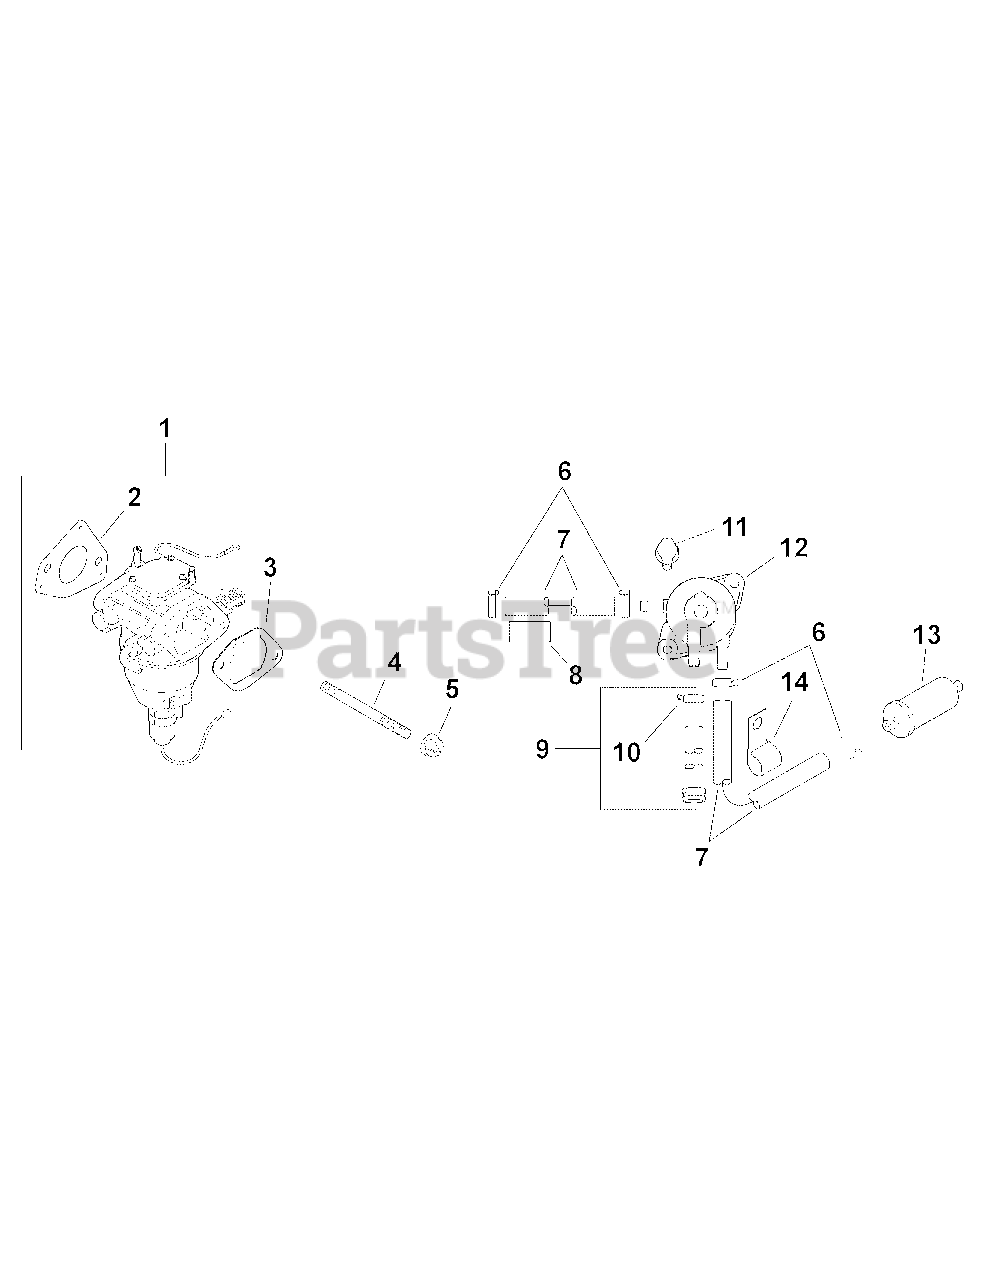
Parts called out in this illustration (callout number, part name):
1	Kit, Carburetor (Incl. 2-3) Model i1046 ONLY
1	Kit, Carburetor (Incl. 2-3) Model i1050 ONLY
2	Gasket, Carburetor
3	Gasket, Air Cleaner Base
4	Stud, M6 x 1.0 x 106
5	Nut, Flange, M6 x 1.0
6	Clamp, Spring Hose 1/2
7	Line, Fuel (24"- Cut to Length
8	Sleeve, Anti Abrasion
9	Kit, Fuel Pump Hose w/Clamp (Incl. 10)
11	Screw, Tap, M6 x 1.7 x 18
